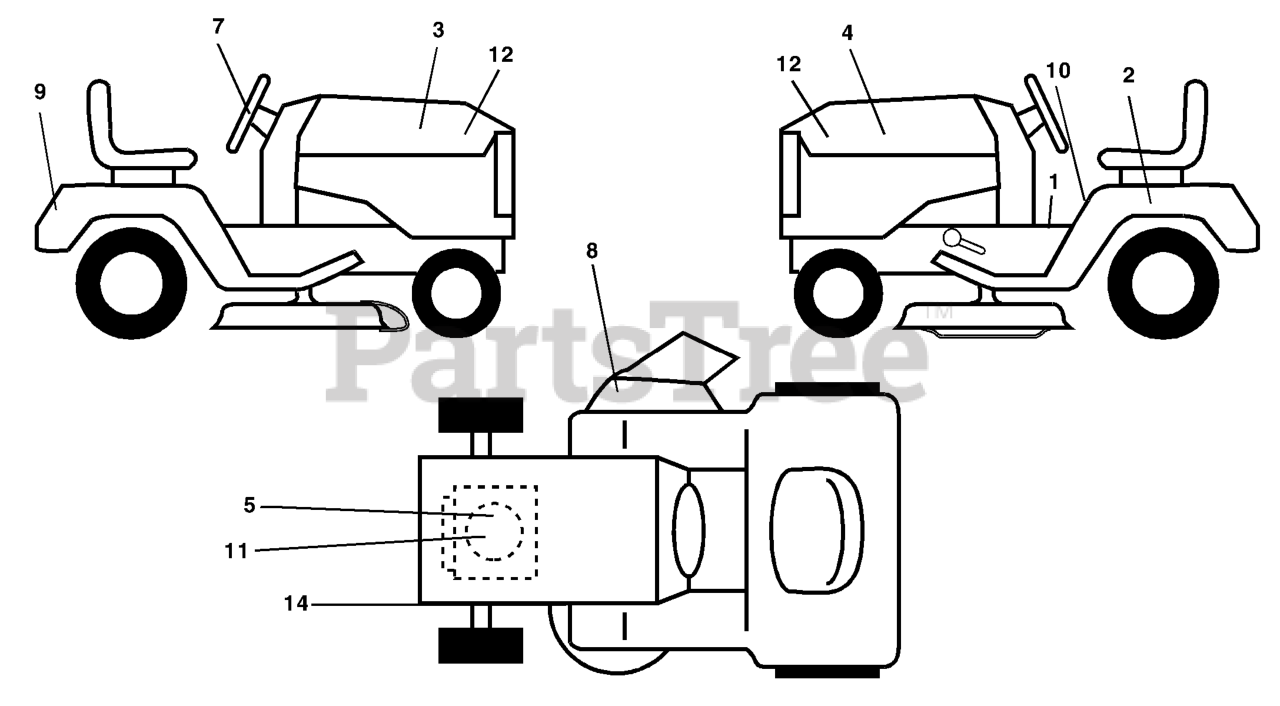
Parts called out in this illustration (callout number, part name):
2	DECAL BTRY SYMBOLS
5	DECAL HP ENGINE
7	DECAL.WHEEL.STEERING.HUSQ.PERM
8	DECAL.WARN.KEEP.HAND.AWAY
9	DECAL, FENDER
10	DECAL FENDER DANGER
11	DECAL, ENGINE LOGO
12	DECAL, HOOD SIDE
14	DECAL V BELT SCHEMATIC
